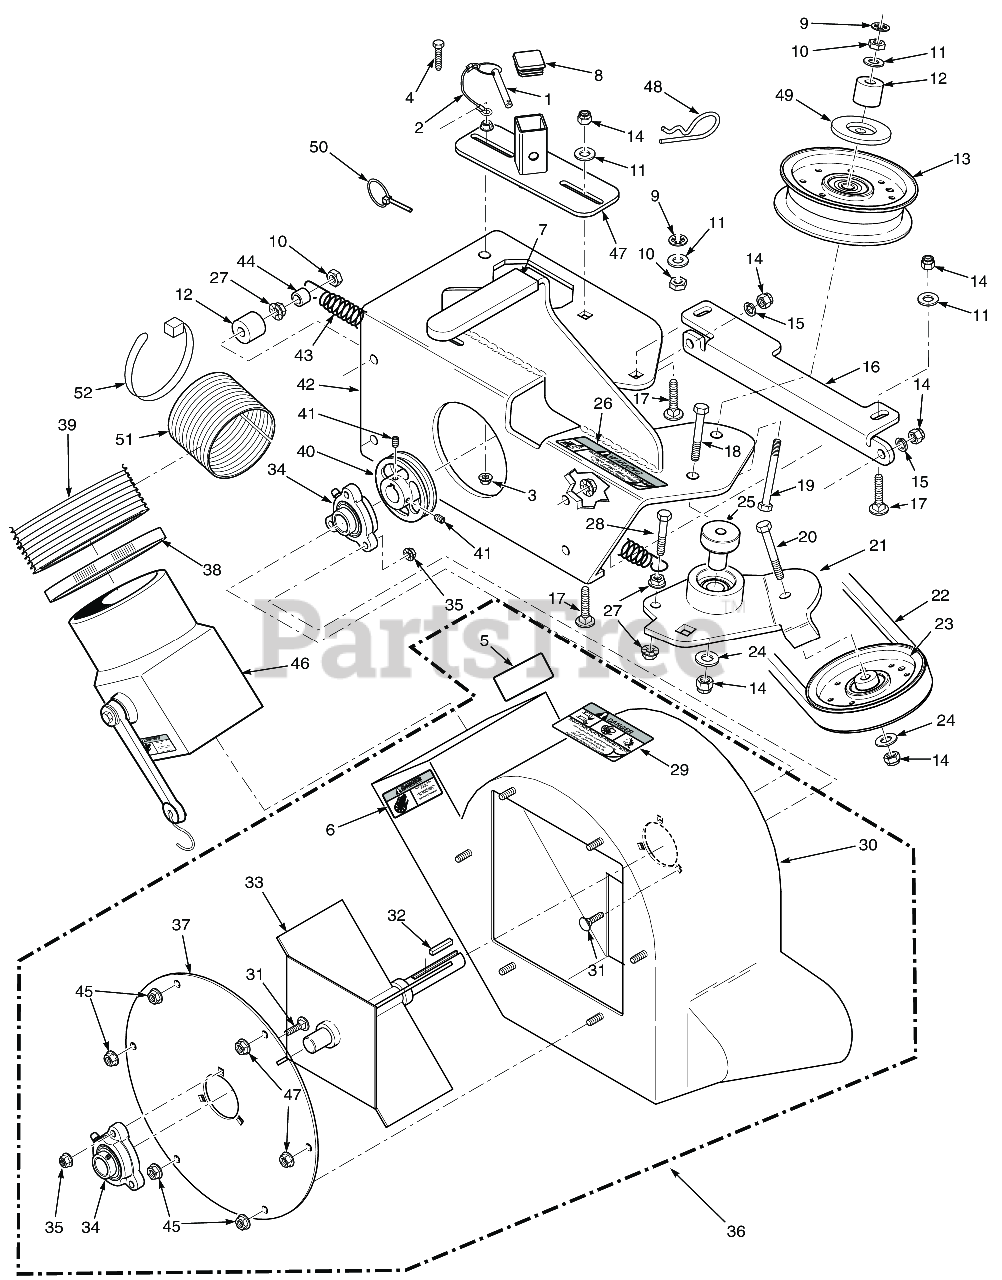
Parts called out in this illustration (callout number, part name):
1	Pin, Ring 1/2 x 2-1/4"
2	Lanyard, Deck Height Pin
3	NUT, 1/4-20 SERRATED FLANGE HEX HEAD
4	NUT, 1/4-20 SERRATED FLANGE HEX HEAD
5	Decal, Blower
6	Decal, Rotating Blower
7	Grip, Deck Latch Lever
8	Cap, Square Vinyl
9	Nut, Push-On - 3/8" Dia.
10	Bolt, Hex Head 3/8-16 x 1" Ser. Flg.
11	Flatwasher, 3/8" Special (.391 x .938 x .105)
12	SPACER, J-PULL ROD
13	Pulley, Idler 3-1/2" Dia. - 52"
14	HEX NUT, ELASTIC STOP LOCK, 3/8-16
15	Lockwasher, 3/8" Spring, Kawasaki FX / FS
16	Plate, Catcher Mounting
17	Bolt, RDHD Carr. 3/8-16 x 1-1/2 (52" & 61")
18	Bolt, Hex Head 3/8-16 x 3" - 52"
19	Bolt, Hex Head 3/8-16 x 3-1/2" Full Thread
20	Bolt, Hex Head 3/8-16 x 1-3/4" (Kohler EFI)
21	Idler Arm Assembly - 52"
22	Belt, GC-SCZ-48V / STCII-48V
22	Belt, GC-SCZ-52V / STCII-52V
23	Pulley, 3-1/2" O.D., GC-STT 52"
24	Flatwasher, 3/8 (.391 x .938 x .105 HD) Grade 8
25	Pivot, Idler - Short
26	Decal, Warning - Belt Cover
27	NUT, 3/8-16 SERRATED FLANGE HEX HEAD
28	Bolt, Hex Head 3/8-16 x 1-1/2" Grade 8 Black
29	Decal, Danger
30	Blower Housing Weldment w/Decals
31	Bolt, 5/16-18 x .75 RHSN Carriage
32	KEY 1/4 X 1/4 X 1 1/2"(FOR 1" CRANKSHAFT
33	Fan Weldment
34	Bearing Assembly
35	HEX NUT, ELASTIC STOP LOCK, 5/16-18
36	Blower Housing Assembly, GC-STT
37	COVER, BLOWER HOUSING
38	Clamp, 8-5/8" Max Dia. (61")
39	Hose, 8.00" Dia. x 53" Long
40	Pulley, 4-3/4" O.D. - 1" Bore
41	Setscrew, Hex Socket Knurl Cup Pt. 5/16 - 18 (nylock)
42	Frame, Blower Mount
43	Spring, Helper (61" Cutter Deck Only)
44	Spacer, Deck Assist
45	Nut, Serrated Flange 5/16-18 (Right Front Engine Mounting, Briggs and Kohler Only)
46	Adapter, Blower GC-STC,
47	Receiver Weldment, Mount Post - 61"
48	Hair Pin Cotter, .177" x 3-1/4"
49	Quick Pin, 5/16" Dia.
50	Quick Pin, 5/16" Dia.
51	Hose, 8" Dia. x 24" Split
52	Cable Tie, .345 X 31.5 Black
